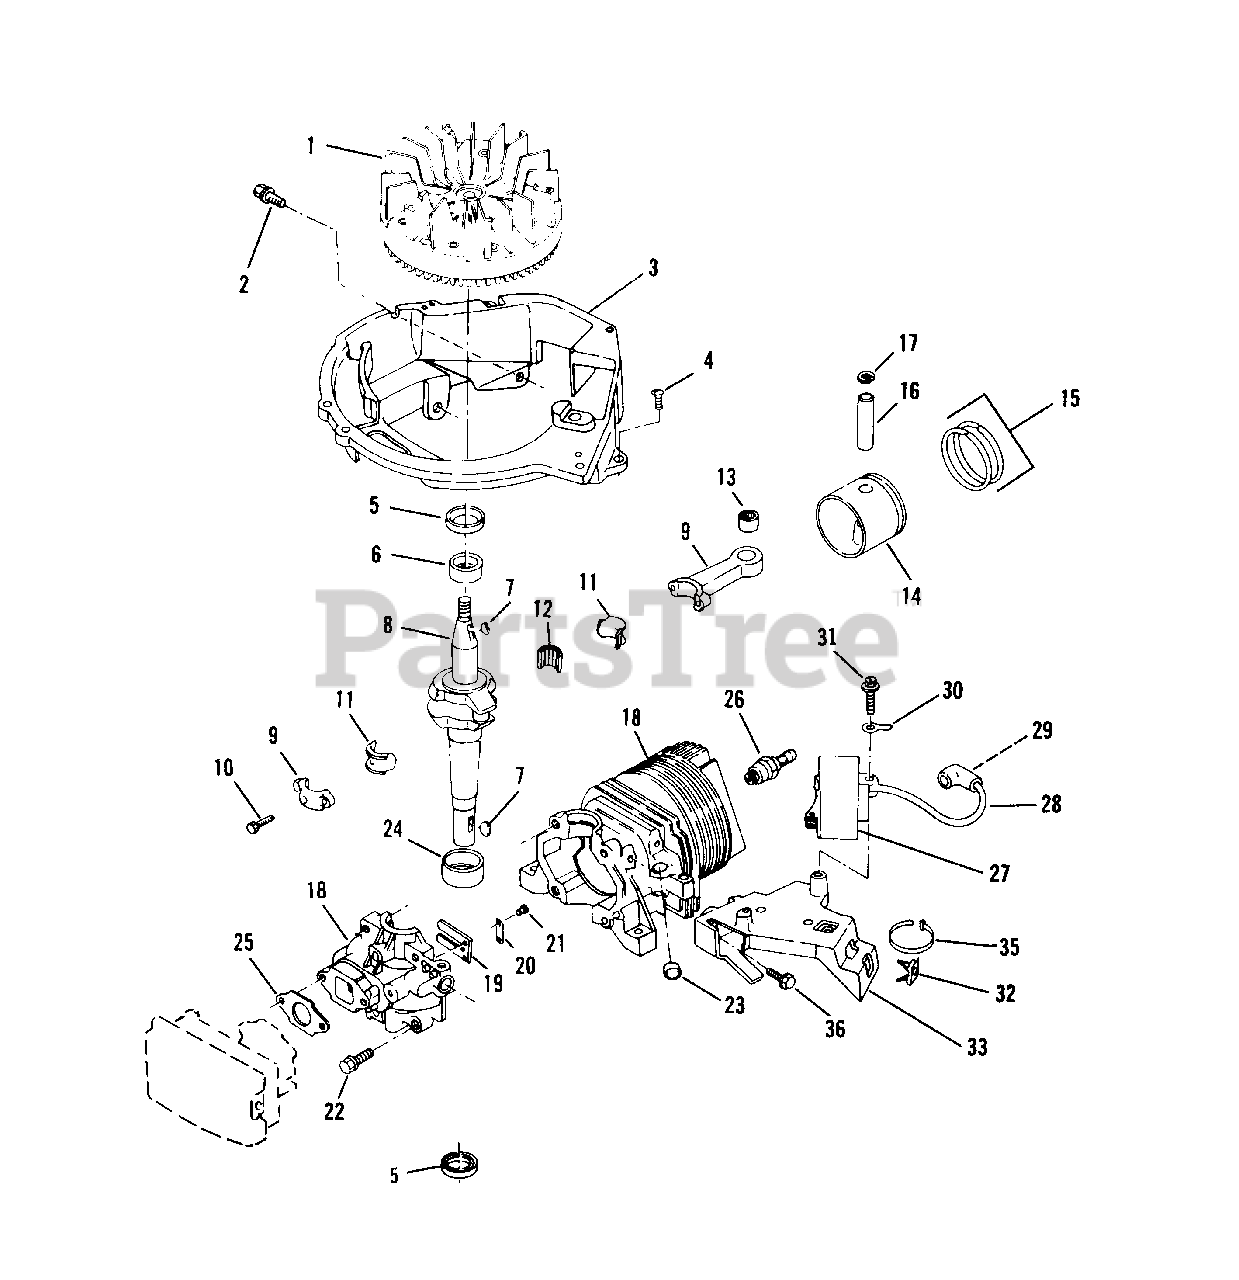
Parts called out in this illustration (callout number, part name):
1	Flywheel Assembly
2	Screw
3	Base-Shroud
4	Screw-Shroud Base to C.D. Brkt.
5	Oil Seal-Crankshaft
6	Bearing-Upper
7	Key-Flywheel and Clutch
8	Crankshaft
9	Connecting Rod Assembly
10	Screw-Cap
11	Liner-Split
12	Needle Bearing Set
13	Bearing Assembly
14	Piston and Ring Set
15	Ring Set
16	Wrist Pin
17	Retaining Ring
18	Cylinder and Crankcase Cover Asy
19	Reed
20	Plate-Reed Hold Down
21	Screw-Reed to C'case Cover
22	Screw-Cover to Crankcase
23	Plug
24	Bearing-Lower
25	Gasket-Carb. to Crankcase Cover
26	Spark Plug
27	C.D. Ignition Module & Lead Asy.
28	High Tension Lead & Cover Asy.
29	Spring Terminal
30	Terminal-Ground Lead
31	Screw-C.D. Mounting
32	Grommet-C.D. Bracket
33	Bracket-Ignition Mounting
35	Tie Strap
36	Screw
